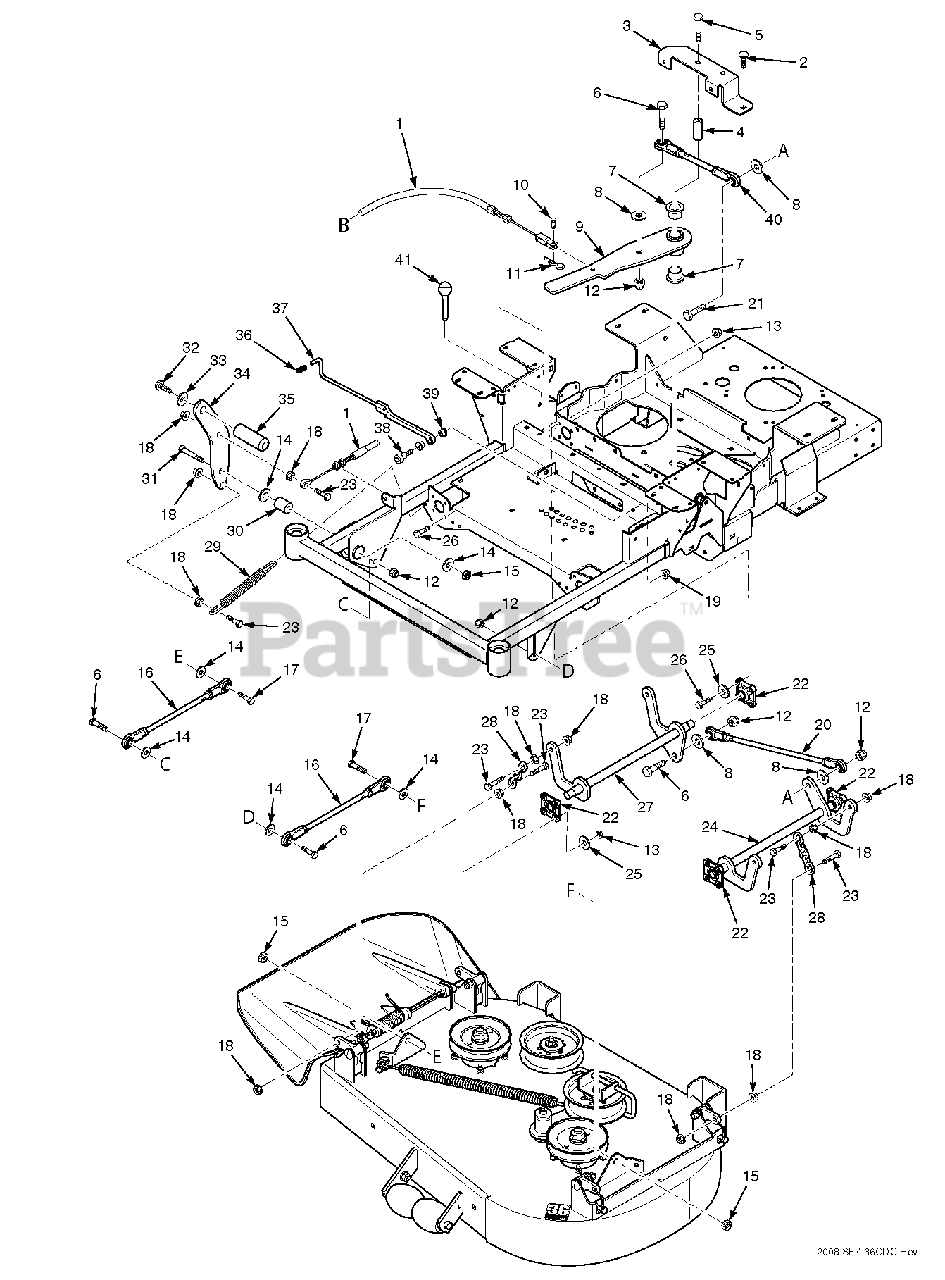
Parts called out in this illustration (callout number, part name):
1	Cable, Deck Lift
2	Bolt, Carriage 3/8-16 x 3/4"
3	Support, Idler Arm
4	Spacer, Deck Lift Pivot
5	Bolt, Hex Head 1/2-13 x 3-3/4"
6	Bolt, Hex Head 1/2-13 x 1-3/4"
7	Bearing
8	Flatwasher, 1/2-.531 x 1.06 x .095
9	Deck Lift Bellcrank Assembly
10	Clevis Pin, 5/16 x 3/4"
11	Hair Pin, .094 x 1.62"
12	Nut, Elastic Stop 1/2-13
13	Nut, Elastic Stop 5/16-18
14	Flatwasher, 1/2-.562 x 1.375 x .109
15	Nut, Center Lock 1/2-13
16	Linkage, Push Arm
17	Bolt, Hex Head 1/2-13 x 1-1/2"
18	Nut, Serrated Flange 3/8-16
19	Nut, Elastic Stop 3/8-16
20	Linkage Assembly, Deck Lift
21	Bolt, Hex Head 1/2-13 x 2-1/2"
22	Bearing, Deck Lift
23	Bolt, Hex Head 3/8-16 x 1-1/2"
24	Weldment, Deck Lift LH
25	Flatwasher, 1/4-.312 x .750 x .065
26	Bolt, Hex Head 5/16-18 x 1"
27	Weldment, Deck Lift RH
28	Chain, Deck lift
29	Spring, Deck Lift
30	Sleeve, Deck Lift Pivot
31	Bolt, Hex Head 1/2-13 x 3"
32	Bolt, Head Socket 5/8-11 x 1-1/2"
33	Lockwasher, 5/8 Spring
34	Pedal, Foot Bracket
35	Foot Pedal
36	Grip, Deck Latch
37	Weldment, Deck Latch
38	Bolt, Shoulder 1/2 x 1/2
39	Bearing
40	Linkage Assembly, Deck Lift
41	Pin, Height Adjuster
